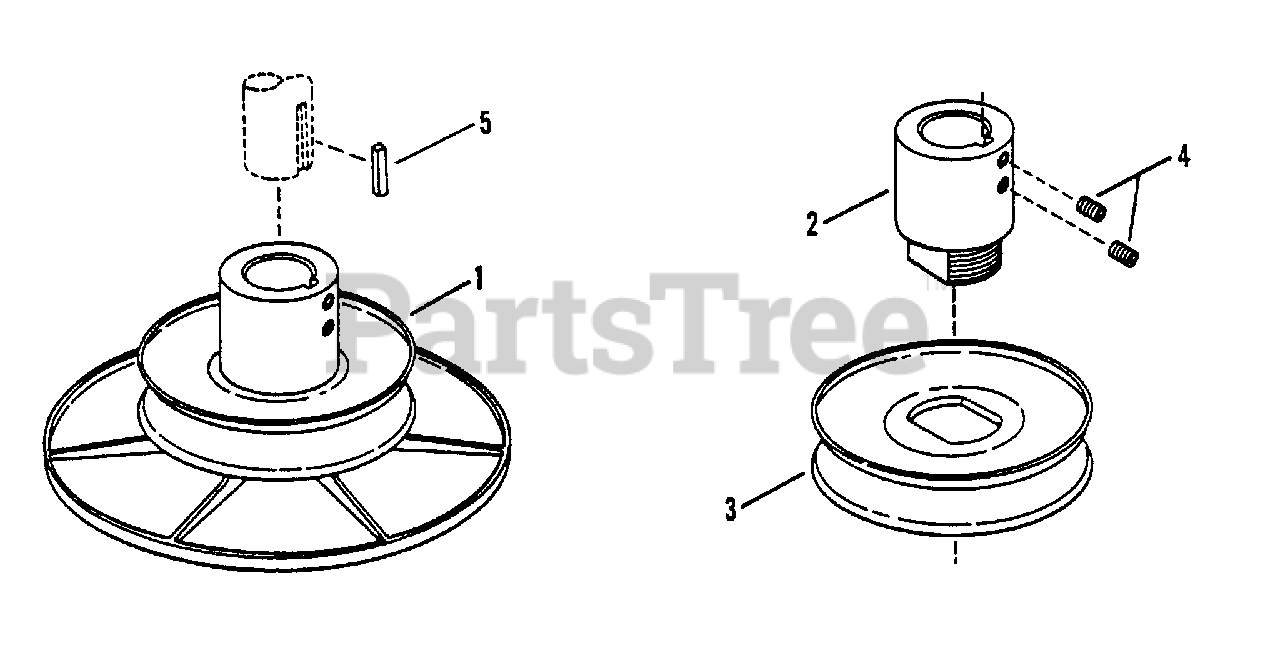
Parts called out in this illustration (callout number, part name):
1	ASSEMBLY, 5.18" O.D. Drive Disc (33" Models)
1	ASSEMBLY, 6" O.D. Drive Disc (25" & 28" Models)
3	PULLEY, Drive (6.0" O.D.) (25" & 28" Models)
4	SET SCREW, 3/8-16 x 3/8"
5	KEY, 1/4" Square x 2"
